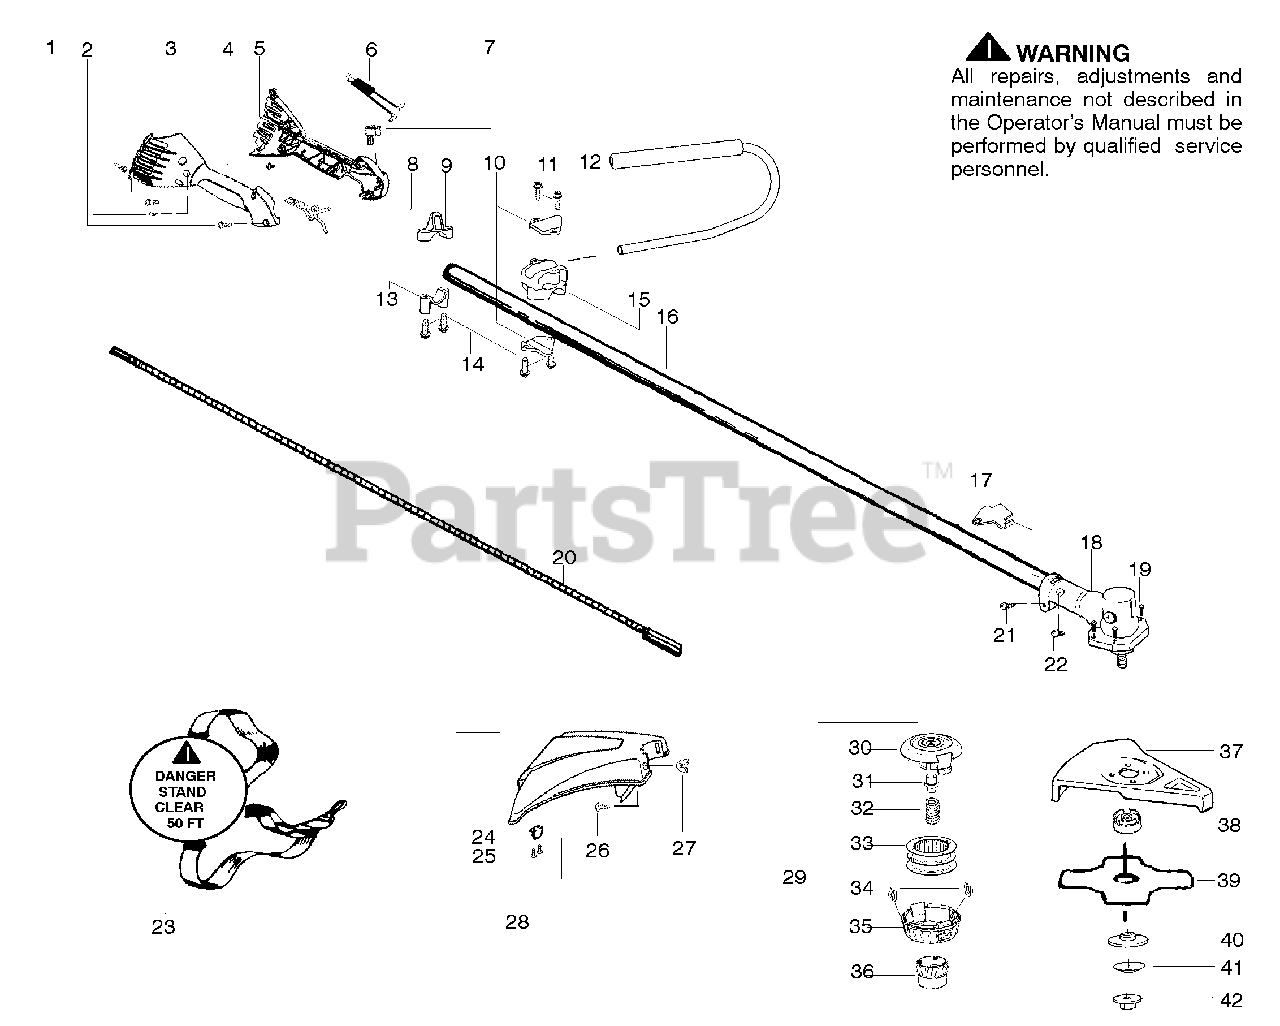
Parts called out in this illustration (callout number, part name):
1	Screw-alignment
3	Hsg.-Throttle-right
4	Screw-Cable Ret.
5	Hsg.-Throttle-left
6	Assy-Wire
7	Kit-Switch
8	Trigger-Throttle
9	Clamp-Harness (upper)
10	Clamp-Bracket
12	Assy.-Handlebar
13	Clamp-Harness (lower)
15	Clamp-Handlebar
16	Kit-Driveshaft
17	Bracket-Shield
20	Shaft-Flex
23	Shoulder Strap
24	Limiter-Line
27	Wingnut
28	Kit-Shield Assy.
29	Assy-TNG VII
33	Accy-Wound Spool
34	Eyelet
35	Cover
37	Kit-Metal Shield
38	Dust cup
39	Accy.-Weed Blade
41	Washer-Belleville
42	Nut-Flange
